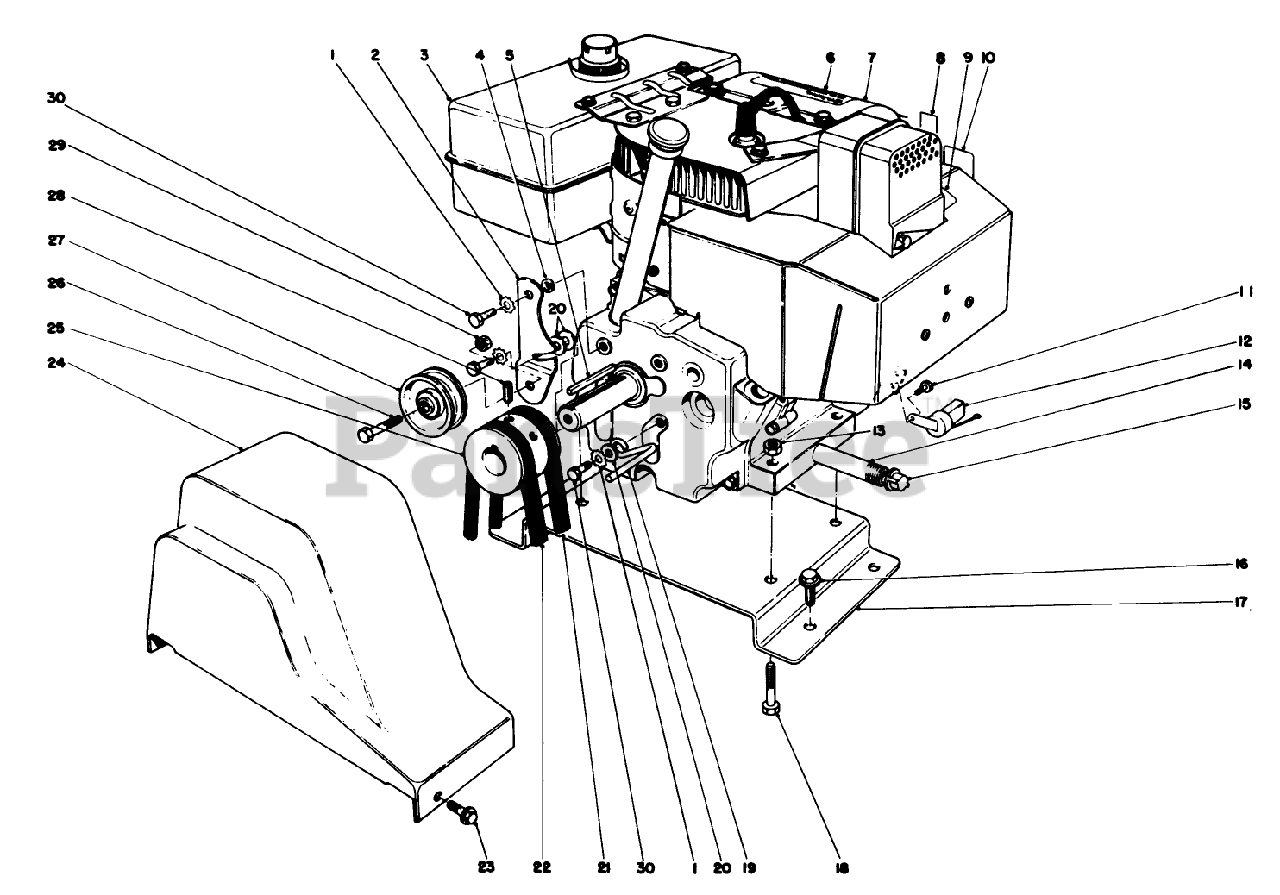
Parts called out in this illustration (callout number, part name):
1	WASHER-LOCK
4	SPACER
6	DECAL - DANGER
7	Engine
8	DECAL-THROTTLE
11	SCREW-HWH
13	NUT-LOCK, NI
15	CAP-PIPE
16	SCREW-HWHTF
18	SCREW-HH
20	WASHER-PLAIN
21	V-BELT
22	V-BELT
23	SCREW-HWH
26	SCREW-HH
27	PULLEY-IDLER
28	SETSCREW
30	SCREW-HH
